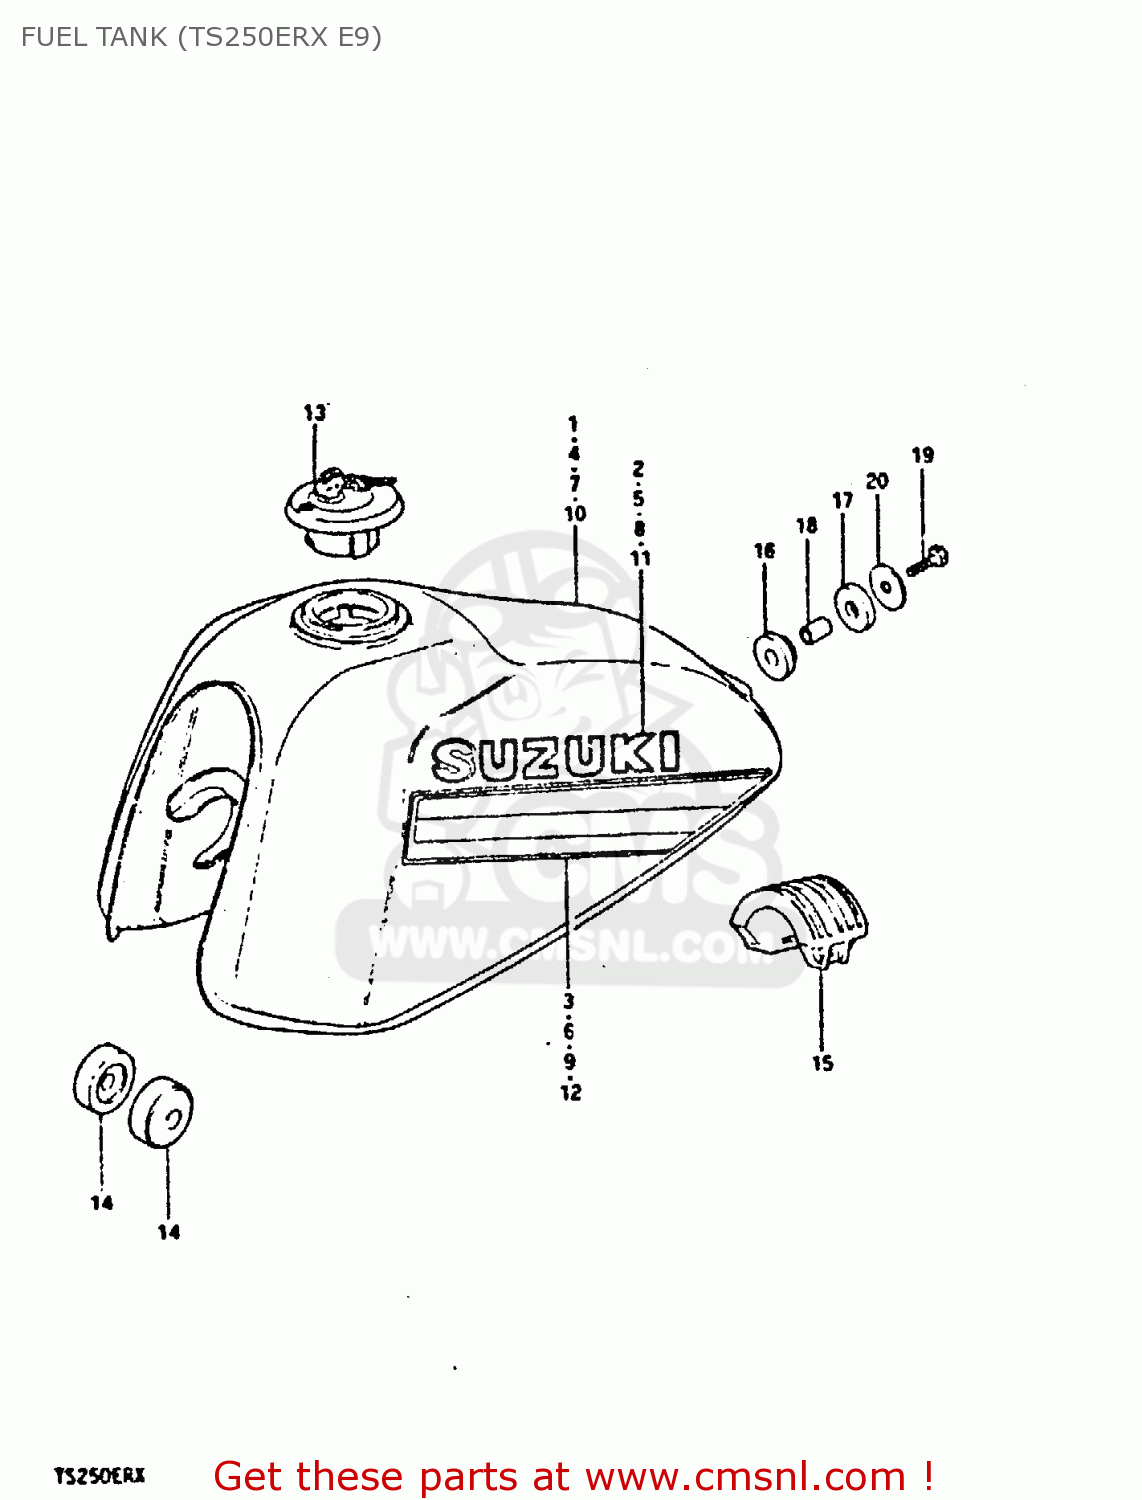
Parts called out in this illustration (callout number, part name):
1	TANK, FUEL (BLUE)
2	EMBLEM
3	TAPE SET
4	TANK, FUEL (RED)
5	EMBLEM (WHITE)
6	TAPE SET
7	TANK, FUEL (YELLOW)
8	EMBLEM(BLACK)
9	TAPE SET
10	TANK, FUEL (WHITE)
11	EMBLEM(BLACK)
12	TAPE SET
13	CAP SET,FUEL TANK
14	CUSHION
15	CUSHION,FUEL TANK
16	CUSHION
17	CUSHION
18	SPACER (8.2X12X17)
19	BOLT (8X30)
20	WASHER (8.5X29X1.6)
